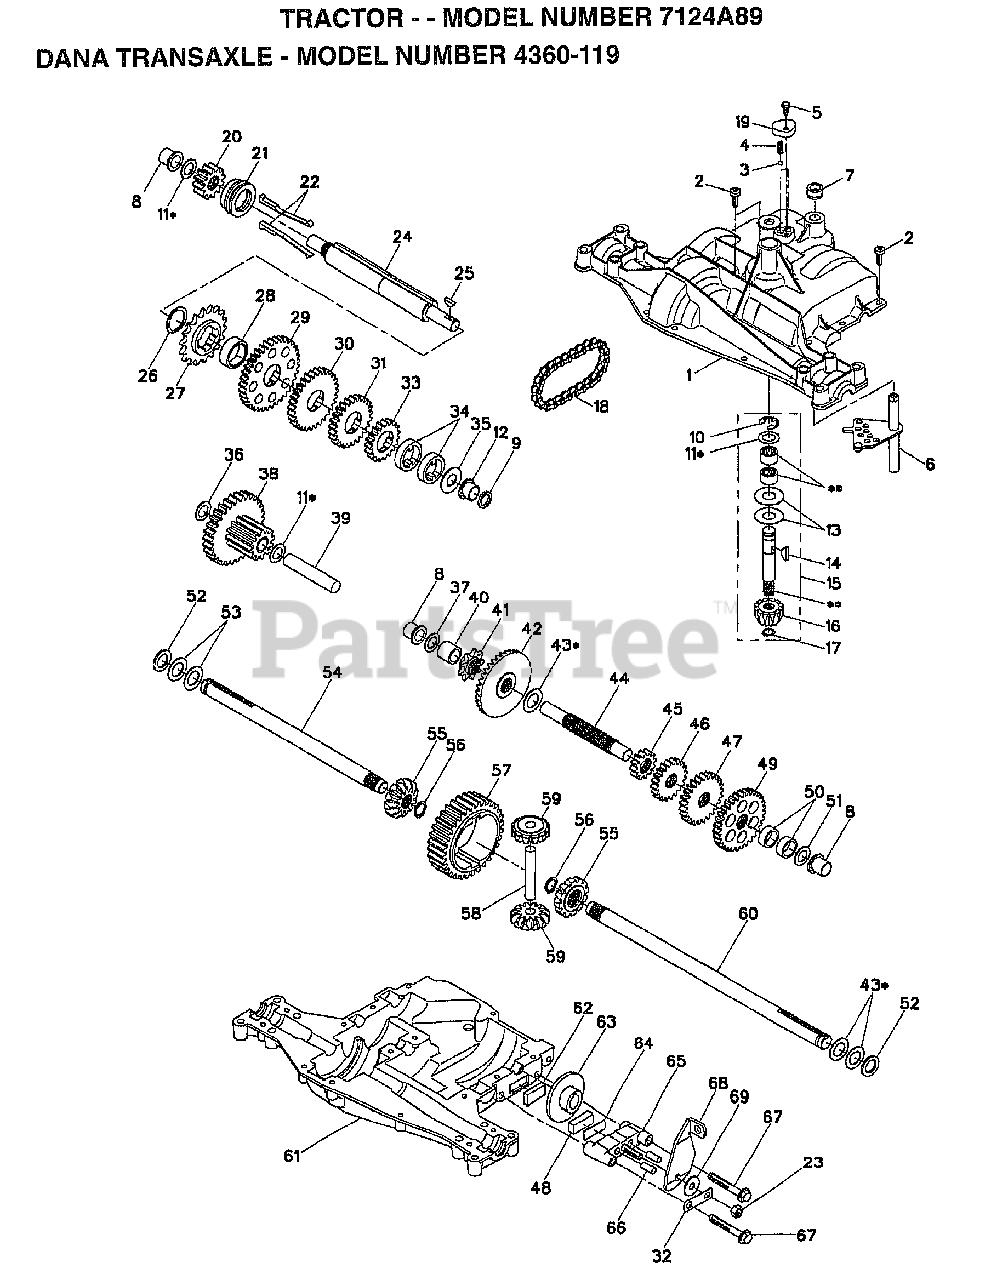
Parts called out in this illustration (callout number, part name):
1	HOUSING.UPPER.DANA.(5305J)
4	"SPRING, DETENT LT"
5	SCREW.TAPPING.1/4-20X.734
6	KIT SHIFTER ASM
9	SEAL.OIL.DAN.5508
10	RETAINING RING LT
11	ASM KIT SHIM 4689
12	BEARING.FLNG.5511
13	WASHER T
14	KEY WOODRUFF-DANA
15	INPUT SHAFT KIT 6250
16	PINION.BEVEL.12T(5620)
17	"RING,RETAINING LT"
18	"CHAIN,24 PTCH LT"
19	COVER.DETENT.(5584)
20	GEAR.SPUR.12T.(5627)
21	CLUTCH.COL.5467
22	ASM KIT CLTCH KEY
23	NUT.LOCK.5/16-24
24	SHAFT INTERM DANA
25	WOODRUFF KEY
26	"RING,RETAINING LT"
27	SPROCKET 18T T
28	SPACER YT
29	GEAR SPUR 37 TTH
30	GEAR SPUR 30T
31	GEAR 25T LT
32	BRACKET, ANTI-ROTATION
33	SPUR GEAR 19T
34	SPACER
35	"WASHER, PLAIN LT"
36	WASHER 045
37	WASHER 031
38	ASSY.GEAR.6153 12T&30T
39	SHAFT IDLER
40	SPACER T
41	SPROCKET 9T LT
42	GEAR.BEVEL.36T(5621)
43	ASM KIT SHIM
44	SHAFT T
45	GEAR SPUR 12 TTH
46	GEAR SPUR 20T
47	"GEAR, SPUR 25T LT"
48	PUCK T
49	"GEAR, SPUR 31T LT"
51	WASHER 060
52	NEOPRENE WASHER
53	WASHER 031
54	AXLE.LH(5528-1)
55	MITER 5270 12T.SPLINED
56	RING.RETAINING.(5270)
58	SHAFT T
59	MITER 5623.12T.IDLER
60	AXLE.LH(5528-1)
61	HOUSING LOWER TNS
62	PUCK T
63	BRAKE DISC. T
64	SPACER LT
66	PIN T
67	SCREW.(5562) .5/16-18X2.35
69	WASHER LT
